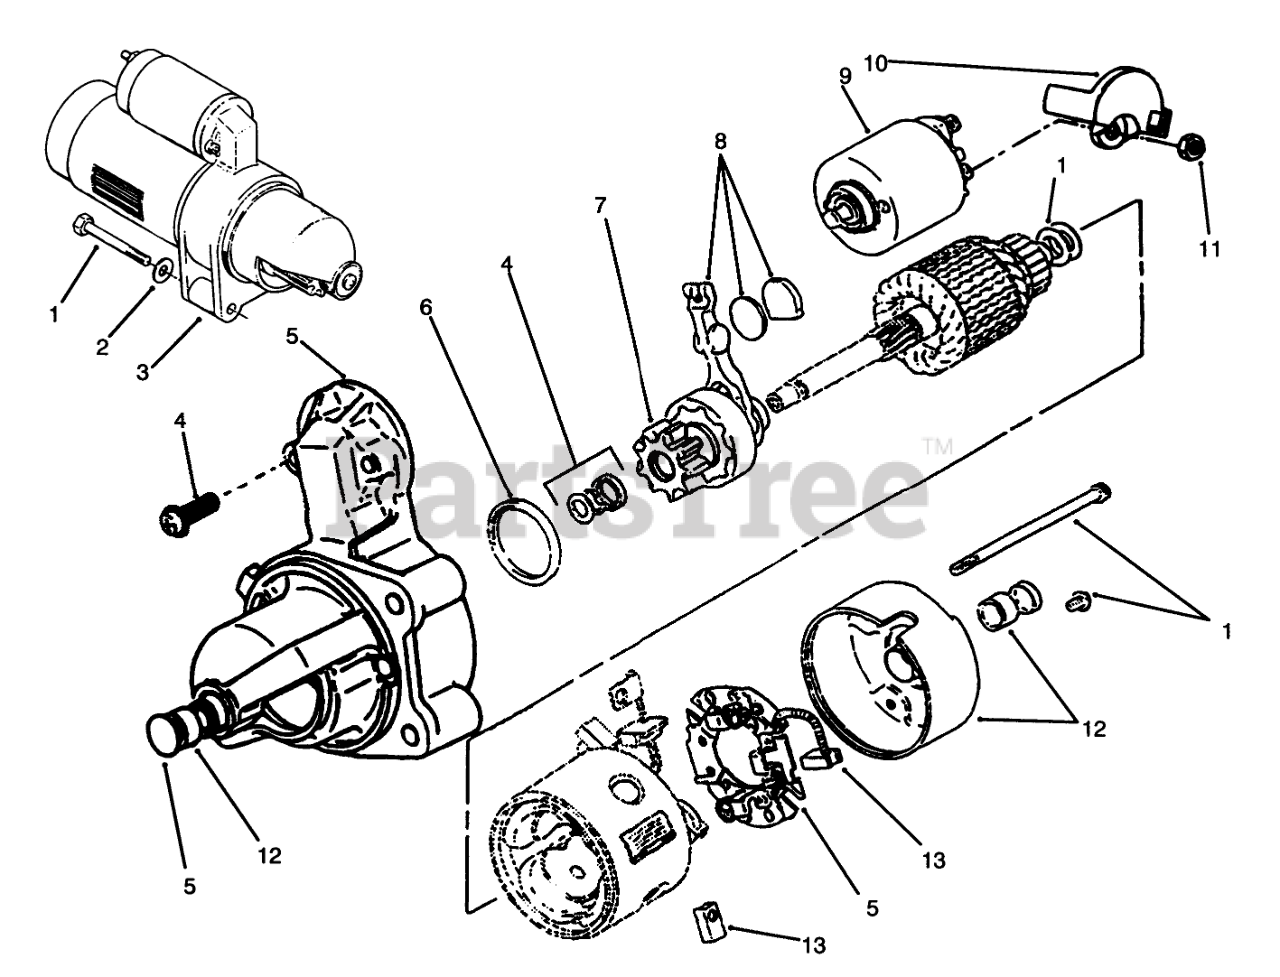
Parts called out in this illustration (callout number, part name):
1	SCREW
2	WASHER
3	STARTER
4	Kit-Hardware, Starter (Includes (2) Solenoid Mtg Screws, 2 Thru Bolts, Armature Shims, Pinion Collar, & Retaining Ring)
5	Kit-Mounting Bracket (Incl. Ref. #13)
6	DUST-SEAL KIT
7	Assembly-Clutch, Starte (Includes Pinion Gear)
8	Kit-Shift Lever, Starter (Includes Lever, Wear Plate & Rubber Plug)
9	Kit-Solenoid, Starter (Includes Solenoid & Spring Plunger)
10	Cap-Starter Solenoid
11	WASHER-FLAT
12	Kit-Bushing, Starter (Incl. Rear Cap with Bushing & Front Bushing)
13	Kit-Brush, Starter (Includes (2) Negative & (1) Positive Brushes)
